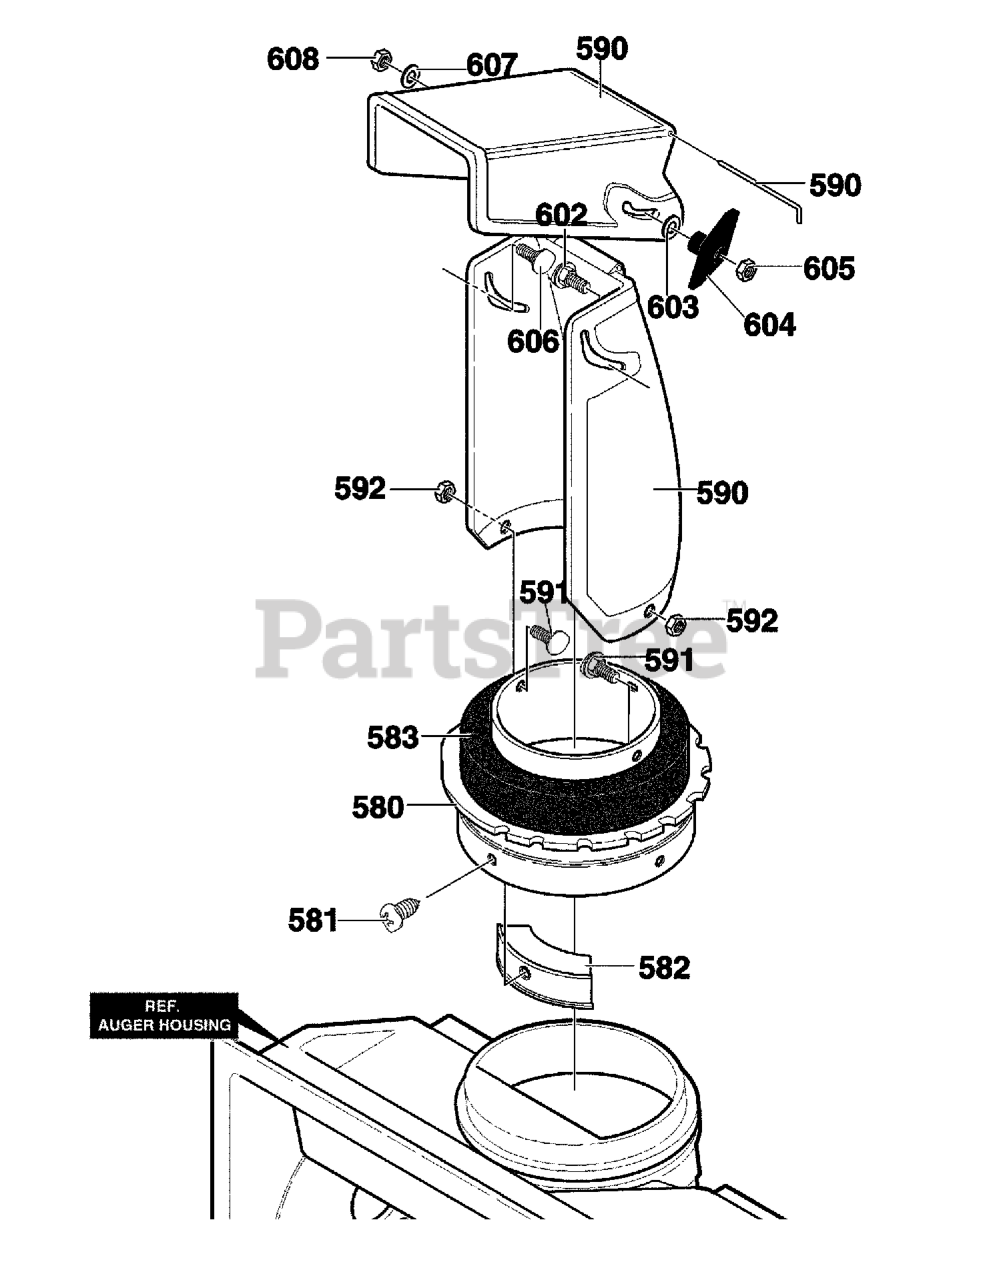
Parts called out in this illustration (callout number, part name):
580	RING, CHUTE
581	SCREW, #10X.50
582	GUIDE, CHUTE
583	DONUT FOAM
590	CHUTE ASSY.
591	SCREW 1/4-20X.50
592	NUT, 1/4-20
602	BOLT, 5/16-18X1.25 CARR.
603	WASHER, FLAT .349X.69X.066
604	KNOB, T
605	NUT, 5/16-18
606	SCREW, 5/16-18 x 0.75
607	WASHER, FLAT .349X.69X.066
608	NUT, 5/16-18
